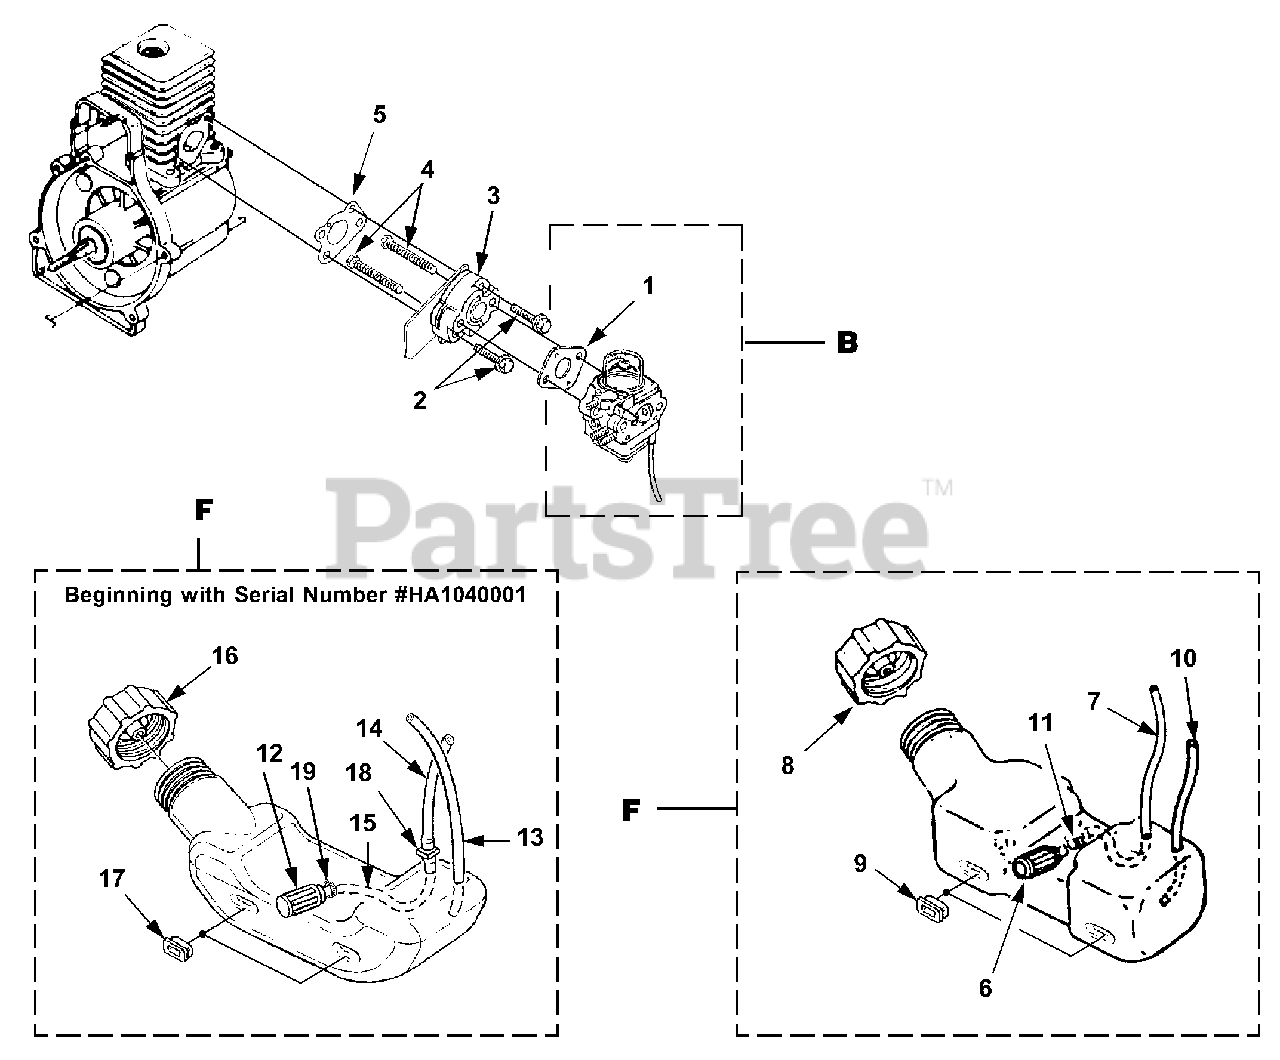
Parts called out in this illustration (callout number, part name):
1	GASKET-Carburetor
2	SCREW, SEMS (10-24 x 1.100)
3	HEAT DAM
4	SCREW- Hex Hd. (10-24 X 2 1/2")
5	GASKET-Heat Dam
6	FILTER-Fuel
7	TUBING-Rubber
8	B FUEL CAP
9	BUMPER-Rubber
10	TUBING-Rubber
11	CLAMP-Wire
12	FILTER-Fuel
13	TUBING-Rubber
14	TUBING-Rubber
15	TUBING-Rubber
16	FUEL CAP
17	BUMPER-Rubber
18	FITTING-Inline
19	CLAMP-Wire
B	CARBURETOR(Walbro)
F	FUEL TANK
F	FUEL TANK ASSY.
